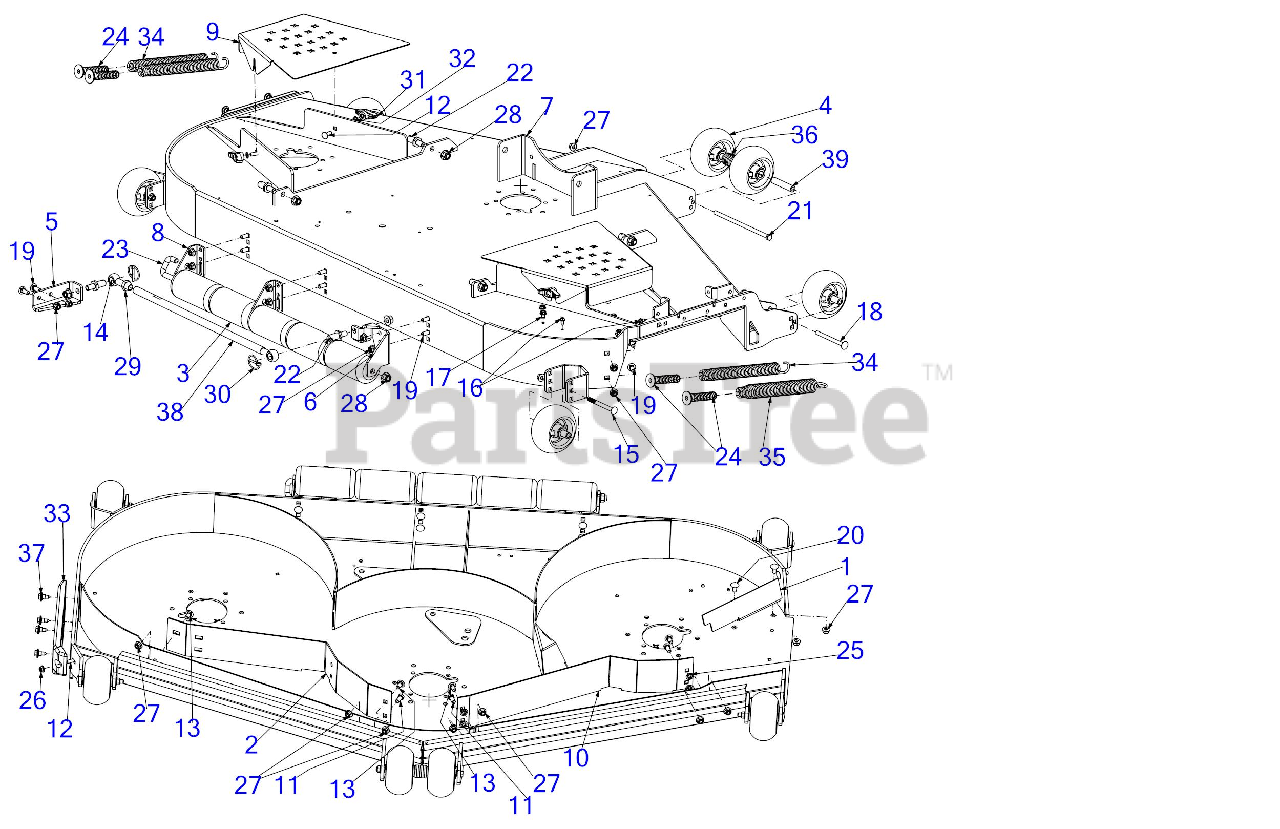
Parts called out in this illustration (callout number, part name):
3	ROLLER ASSEMBLY
4	5" DIA DECK WHEEL COMPLETE
11	HEX SCREW 3/8-16 x .75
12	CARRIAGE BOLT 5/16-18 x 1.00
13	CARRIAGE BOLT 3/8-16 x .750 GR5
14	BOLT 5/8-16 x 2.63
15	CARRIAGE BOLT 3/8-16 x 4.00 GR5
16	SCREW 1/4-20 X.500
17	SCREW 5/16-18 x .500
18	CARRIAGE BOLT 3/8-16 x 4.25 GR5
19	CARRIAGE BOLT 3/8-16 x 1.00 GR5
20	CARRIAGE BOLT 3/8-16 x .75
21	SCREW 3/8-16 x 8.5 GR5
23	REAR ROLLER PIN
24	SPRING INSERT SCREW
26	FLANGE LOCK NUT 5/16-18
29	HEX NUT
31	WING KNOB 5/16-18
33	DECK SKID PLATE (LH)
34	EXTENTION SPRING 1.20 x 11.35
35	EXTENSION SPRING 1.44 OD X 11.36
36	FLAT WASHER
37	SHOULDER SCREW .43X.29X5/16-18 TT
39	WHEEL SPACER .38ID x 3.04LG
